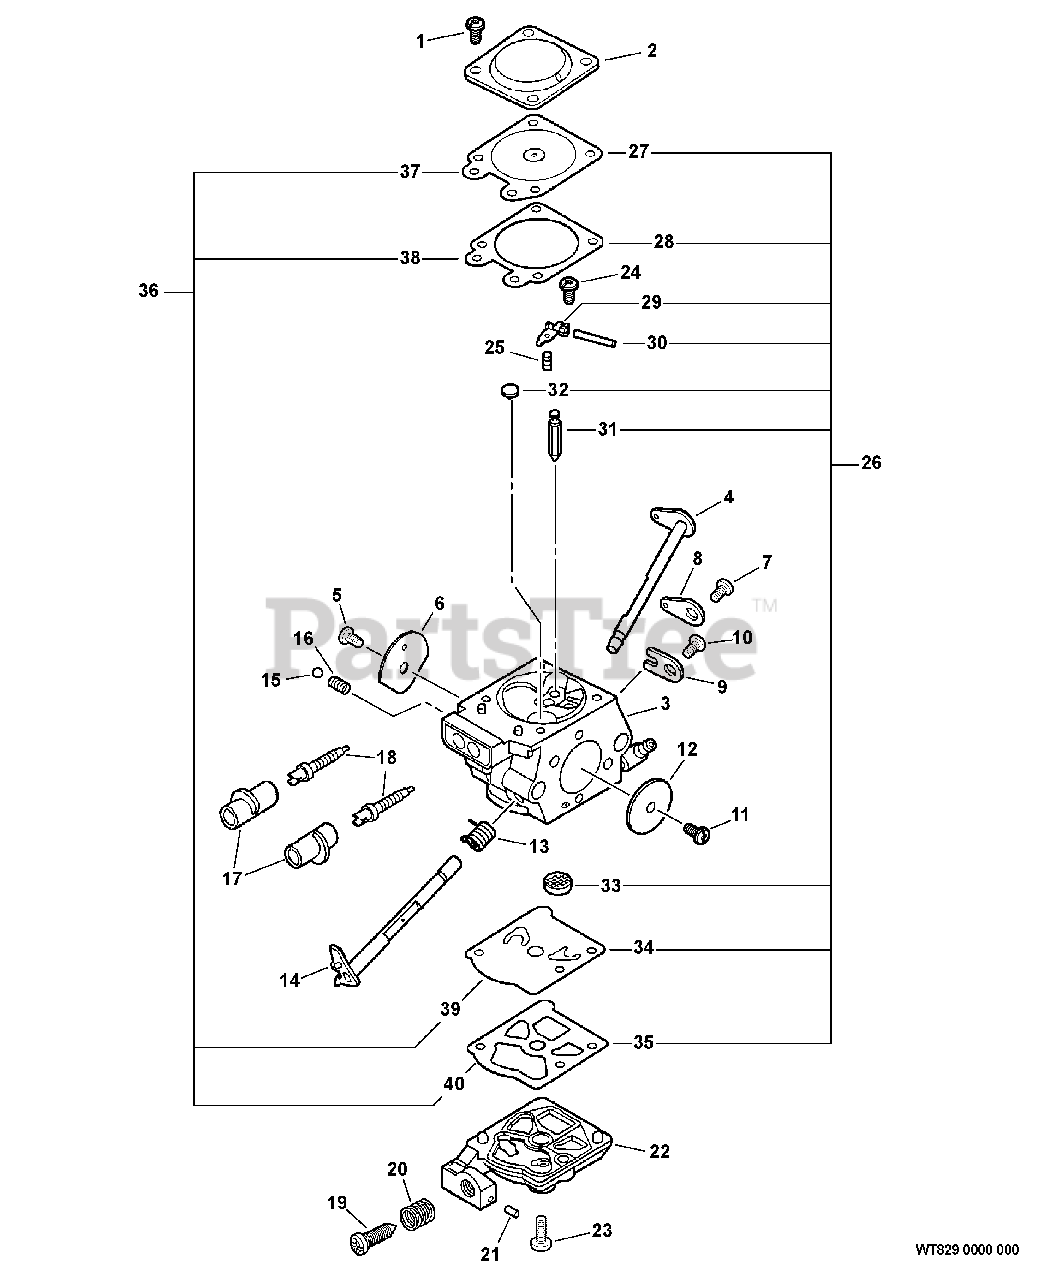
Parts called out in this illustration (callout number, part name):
2	COVER, METERING
3	BODY, CARBURETOR
4	SHAFT, CHOKE
6	VALVE, CHOKE
8	LEVER, THROTTLE
9	CLIP, THROTTLE SHAFT
12	VALVE, THROTTLE
13	SPRING, THROTTLE RETURN
14	SHAFT, THROTTLE
16	BALL, CHOKE
17	CAP, LIMITER
18	NEEDLE - MIXTURE
19	SCREW, IDLE ADJUST
20	SPRING, IDLE ADJUST
22	COVER, PUMP
23	SCREW, PUMP COVER
24	SCREW, METERING LEVER PIN
25	SPRING, METERING LEVER
26	REPAIR KIT
27	DIAPHRAGM, METERING
28	GASKET, DIAPHRAGM
29	LEVER, METERING
30	PIN, METERING LEVER
31	VALVE, INLET NEEDLE
32	PLUG, WELCH
33	STRAINER
34	DIAPHRAGM, PUMP
35	GASKET, PUMP
36	DIAPHRAGM/GASKET KIT
37	DIAPHRAGM, METERING
38	GASKET, DIAPHRAGM
39	DIAPHRAGM, PUMP
40	GASKET, PUMP
